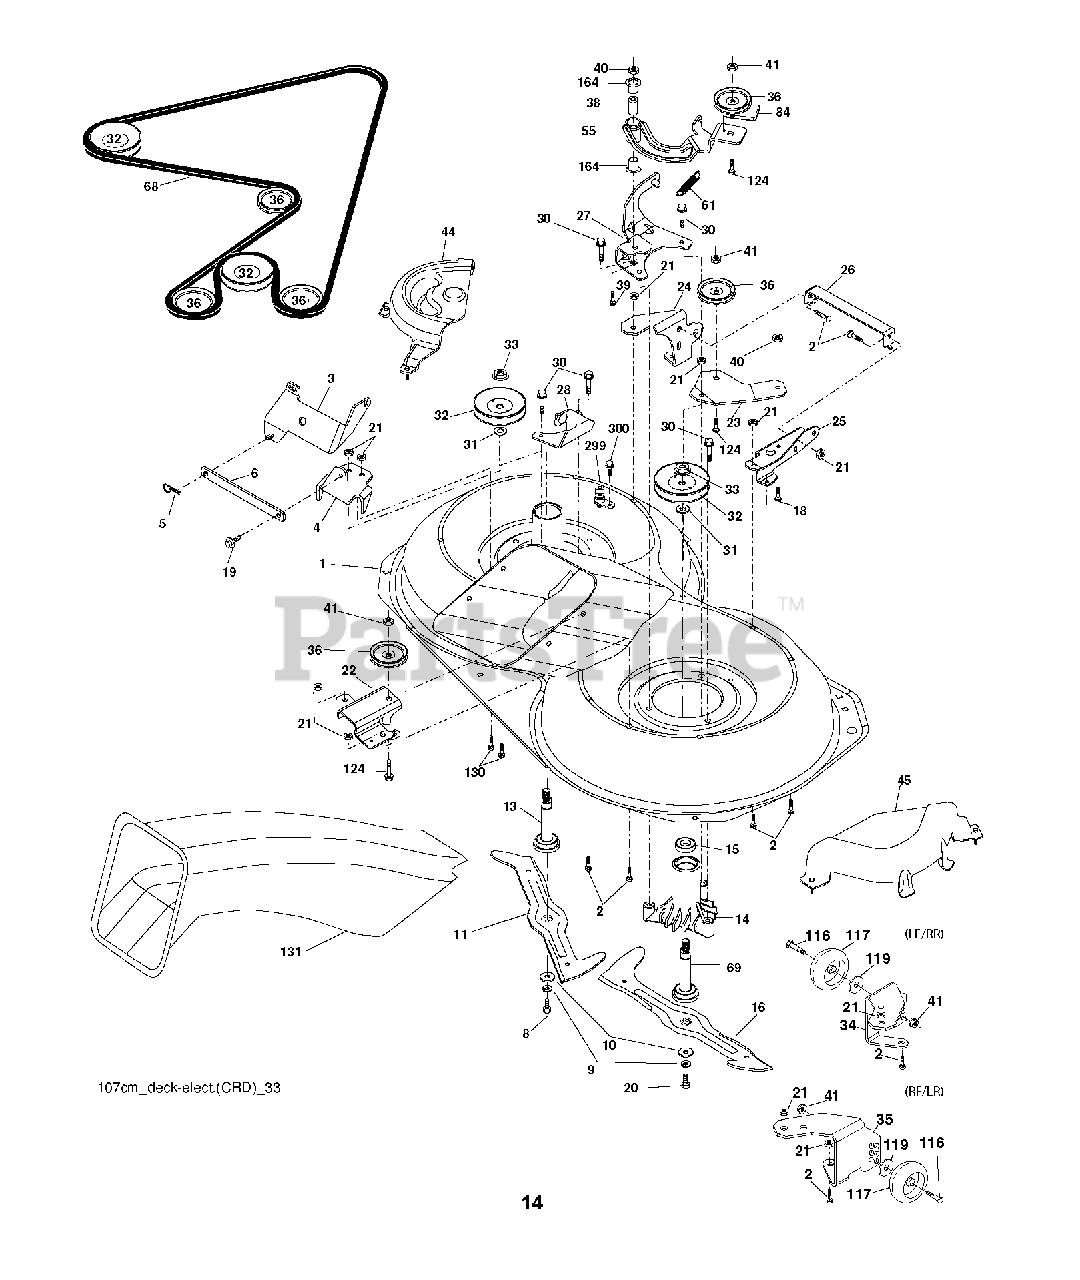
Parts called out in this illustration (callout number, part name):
2	BOLT 5/16-18 X3/4 ZN/YEL GR 5
3	BRACKET.ASM.BAR.SWAY.CHASS
5	Retainer Spring
6	BAR.SWAY.92.CRD
8	BOLT.3/8-24X1.25 GR8
9	LOCKWASHER
10	WASHER.BLADE
11	BLADE.3N1.LH.CRD
13	SHAFT ASM VENT
14	HOUSING.MANDREL.VENTED (MACHD)
16	BLADE.3N1.RH.CRD
19	BOLT SHD 5/16-18
20	BOLT.3/8-24X1.25GR8. LHTHRD
21	LOCKNUT
22	BRACKET.IDLER.RR.107.CRD
24	BRACKET
25	BRACKET RF
26	SUPPORT
28	BRACKET
30	SCREW, WASHER HEAD
31	WASHER.SPACER.MANDREL
32	PULLEY.MANDREL.4.80 PD.2006
33	NUT.FLANGE.LOCK.TOP
34	BRACKET
35	BRACKET
36	PULLEY.IDLER.4.25
41	NUT LOCK FLG 3/8-16 UNC
55	ARM.IDLER.107.CRD
61	SPRING
68	HEX-BELT 107 MOWER
69	SHAFT.ASM.W/LWR.BRG.RH.THREAD
84	KEEPER, BELT IDLER
116	BOLT.SHOULDER.3/8-16X3-5/8.
117	WHEEL. GUAGE RALLY
119	WASHER
124	BOLT.3/8-16X1.50
130	BOLT.CARR.SQNK.5/16-18UNC.X3/4
131	CHUTE BAGGER
164	BRNG T
299	PORT.WASHOUT
300	SCREW.TT.#10-32X.5.3/8.FLANGE
